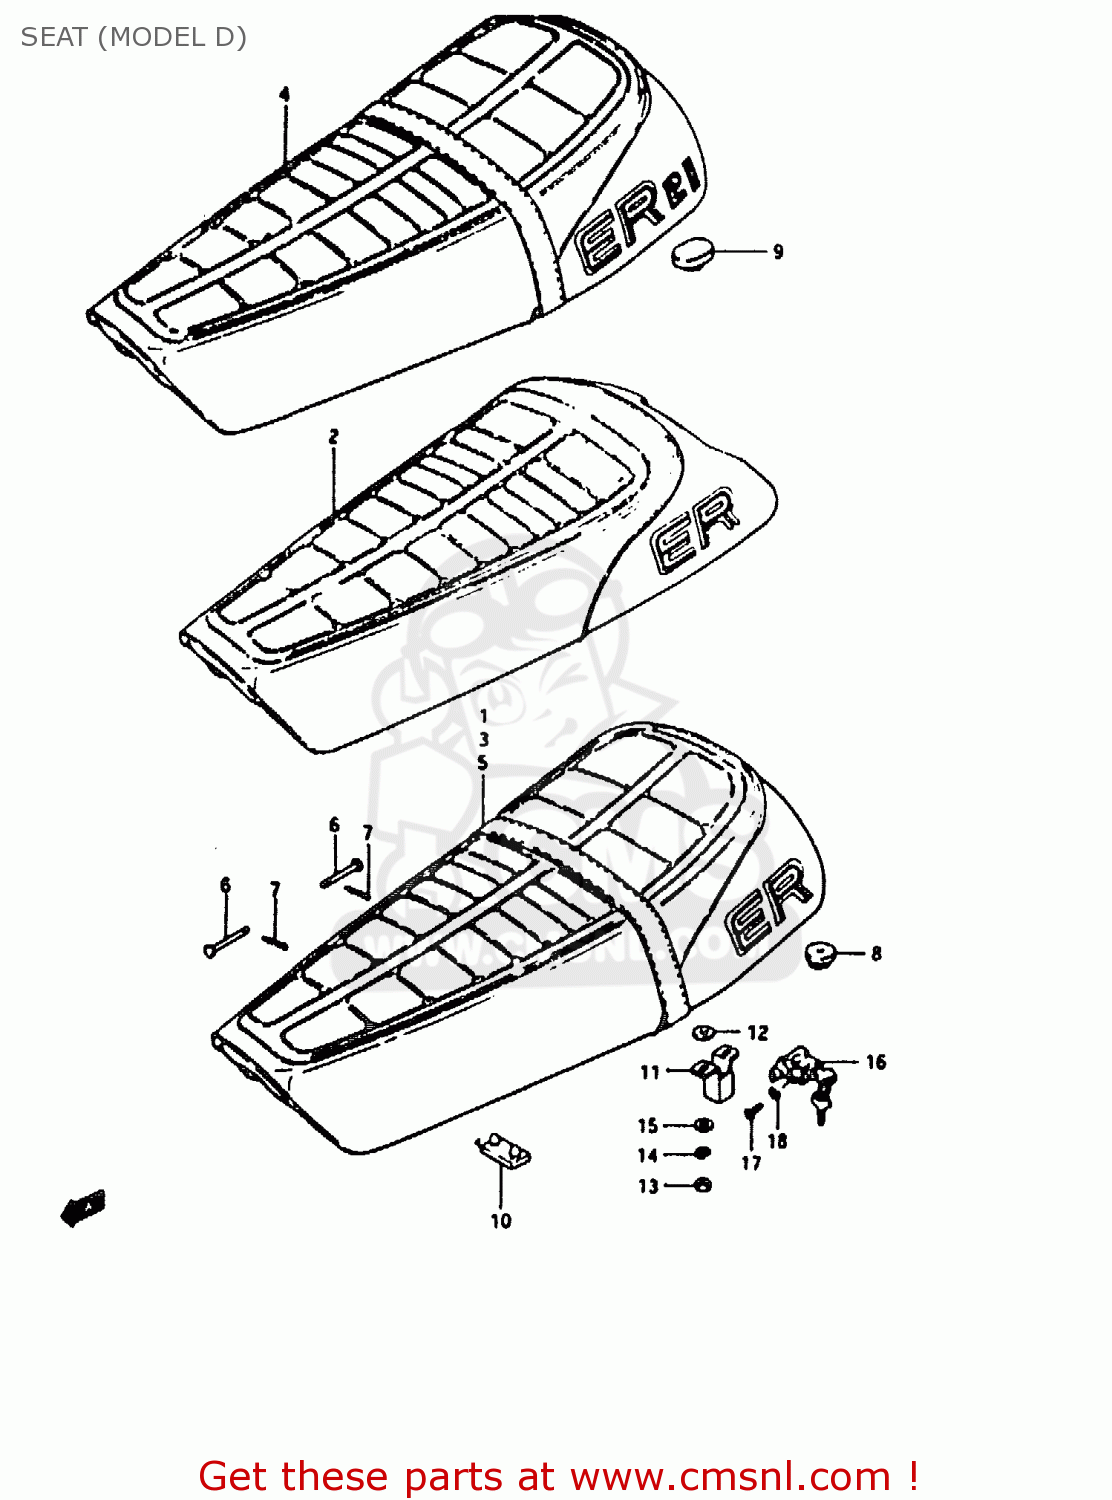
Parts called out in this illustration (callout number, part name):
1	SEAT ASSY (BLUE)
6	PIN
7	PIN
8	CUSHION(11.5X22X20)
10	CUSHION
11	PLATE,CLAMP GUIDE
12	WASHER(8.5X18X1)
13	NUT
14	LOCK WASHER
15	WASHER
16	LOCK ASSY,SEAT
17	SCREW
18	LOCK WASHER
